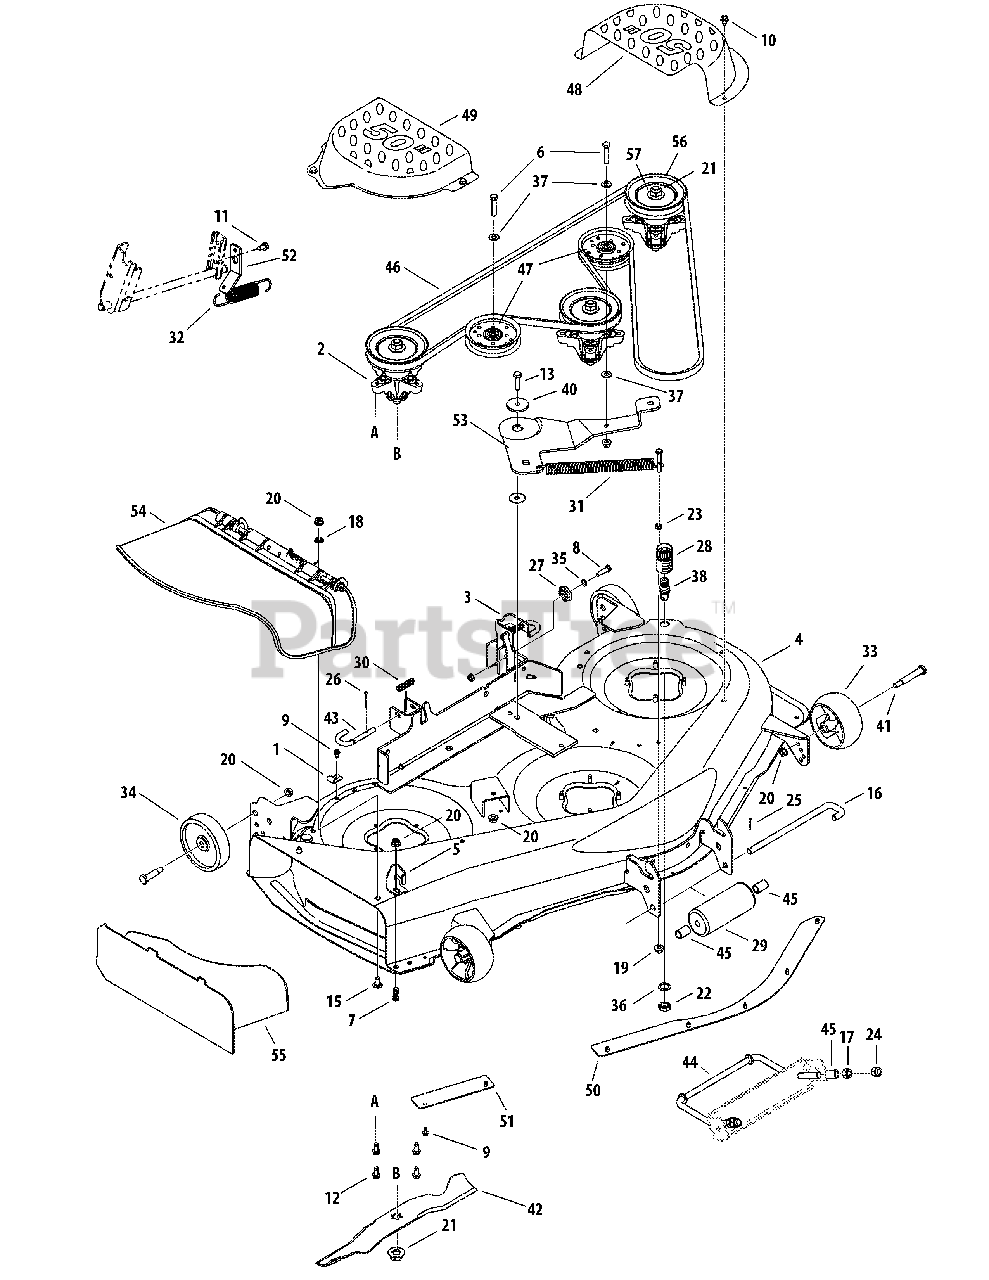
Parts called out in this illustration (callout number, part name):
1	Retainer Hook Brkt.
2	Spindle Assembly
4	50" Deck (weldment)
6	Hex Screw 3/8-16 x 1.75
7	Screw, 3/8-16 x 1.0
8	Hex Bolt 5/16-18 x 1.25
9	Hex Wash S-Tapp Scr 1/4-20 x .50
10	Hex Wash HD AB Tap Scr 5/16-18 x .75
11	Hex Wash HD AB Tap Scr 5/16-12 x .75
12	S-Tapp Scr 5/16-18 x .75
13	Screw, 3/8-16 x 1.25
14	Hex Hd Cap Scr. 5/16-18 x 2.0 Gr. 5
15	Short Neck Carriage Bolt 3/8-16 x .75
16	Pin, Roller, .50" Dia. x 10.06
17	Hex Nut 1/2-13
18	Push Nut 3/8
19	Flange Locknut 5/16-18 Gr. F, Nylon
20	Flange Lock-Nut 3/8-16 Gr. F Nylon
21	Hex Flange Nut 5/8-18
22	Hex Nut, M16-1.5
23	Hex Nut 5/16-18 hd. Gr. 5
24	Hex L-Nut 1/2-13
25	Cotter Pin 3/32 x 1.0
26	Cotter Pin 1/8" Dia x 1.25
27	Deck Adjustment Gear
28	Water Nozzle Adaptor
29	Front Roller
30	Compression Spring .531 OD x 1.75 Lg.
31	Extension Spring .94 x 6.74
32	Extension Spring 1.5 x 5.99
33	Deck Wheel 5.0
34	Wheel Ass’y - Deck 5" x 1.38"
35	L-Wash 5/16 ID
36	Lockwasher 5/8
37	Flat Washer .406 x .875 x .059
39	Shoulder Bolt .498 Dia x 1.53 x 3/8-16
40	Spacer, Shoulder .884 x .190
41	Shoulder Screw
42	Blade 17.90
43	Deck Release Pin
44	Deck Adjustment Rod
45	Spacer .55 ID x .75
46	V-Belt
47	Idler Pulley w/Flange 4.25 Dia
52	Lift Bracket
54	Side Chute Assembly
55	Mulching Plug
56	Deck Pulley 5.39 Dia.
57	Flat Washer .76 ID x 1.5 OD x .12
